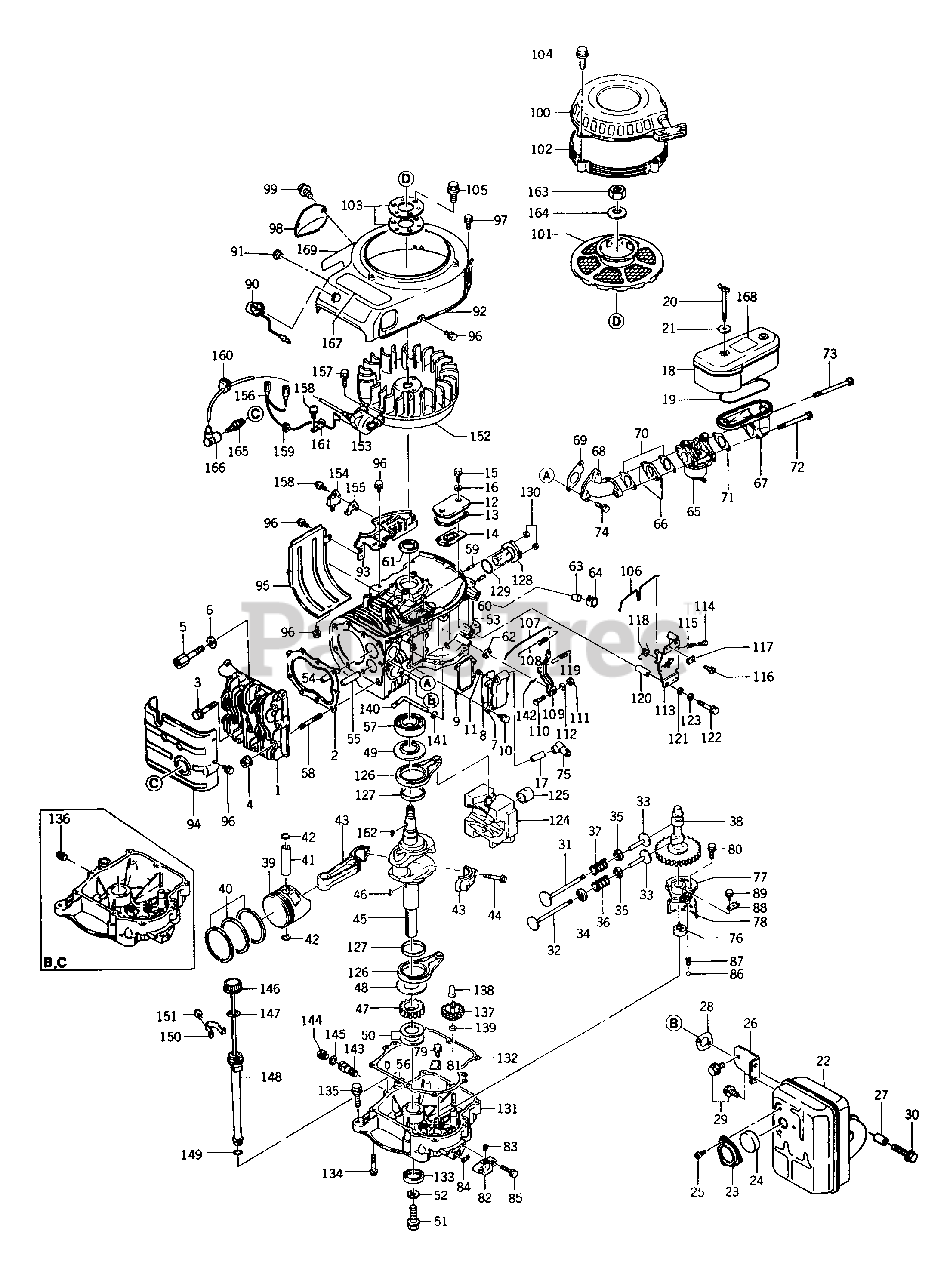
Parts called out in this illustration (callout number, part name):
1	HEAD, cylinder
2	GASKET, head
3	BOLT (10x55)
4	NUT (10mm)
6	WASHER
7	COVER, valve chamber
9	GASKET
10	BOLT (6x16)
11	SCREW
15	BOLT
16	GASKET
18	AIR FILTER ASS'Y
19	GASKET
22	MUFFLER ASS'Y
23	CAP
24	ARRESTER, spark
25	SCREW (5x8)
28	GASKET
29	BOLT (8x12)
30	BOLT (8x45)
31	VALVE, intake
32	VALVE, exhaust
35	RETAINER, spring
36	SPRING, valve
37	SPRING, valve
38	SHAFT, cam
39	PISTON
40	PISTON RING SET
41	PIN, piston
42	RING, snap
43	CONNECTING ROD ASS'Y
44	BOLT, connecting rod
45	CRANK SHAFT COMP
47	GEAR, helical
49	SPACER
50	SHIM
53	CRANK CASE COMP
54	GUIDE, valve (IN)
55	GUIDE, valve (EX)
56	PIN, dowel
57	BEARING, ball (6207)
61	SEAL, oil
62	SEAL, oil
64	CLIP
65	CARBURETOR ASS'Y
67	PIPE, intake
68	PIPE, intake
69	GASKET
70	GASKET
71	GASKET
74	BOLT (8x25)
76	OIL PUMP ASS'Y
77	PUMP COVER COMP
78	FILTER, oil
79	BOLT (5x8)
80	BOLT (8x25)
83	PLUG
85	BOLT (8x30)
86	BALL, steel
88	PLATE
89	BOLT (6x10)
91	GROMMET
92	HOUSING, fan
93	HOUSING, fan
95	SHROUD
96	BOLT (6x10)
97	BOLT (6x14)
99	SCREW (4x8)
100	RECOIL STARTER ASS'Y
101	PULLEY
104	BOLT (6x35)
105	BOLT (8x12)
106	LINK, choke
107	LINK
109	GOVERNOR ARM COMP
111	NUT (6mm)
112	WASHER
113	CONTROL PANEL ASS'Y
114	SCREW (4x25)
115	SPRING
116	BOLT
119	SPRING
121	WASHER
122	BOLT (6x50)
123	WASHER, spring
124	WEIGHT COMP
125	BEARING, plane
126	ROD ASS'Y
127	BEARING, plane
130	NUT
131	CRANK CASE COVER COMP
132	GASKET
133	SEAL, oil
134	BOLT (8x45)
135	BOLT (8x25)
136	PLUG
137	GOVERNOR ASSAY
138	SLEEVE
139	WASHER
140	ARM, pivot
141	WASHER
142	PIN, snap
144	PLUG
145	GASKET
147	GASKET
149	O-RING
150	CLAMP
151	BOLT (5x8)
152	FLYWHEEL COMP
153	COIL, ignition
154	IGNITER
155	BRACKET
156	WIRE, lead
157	BOLT (5x25)
158	SCREW (4x8)
161	CLAMP
163	NUT (18mm)
165	PLUG, spark (BMR 4A)
166	CAP, spark plug
167	LABEL, brand
168	LABEL, manual
169	LABEL, manual
